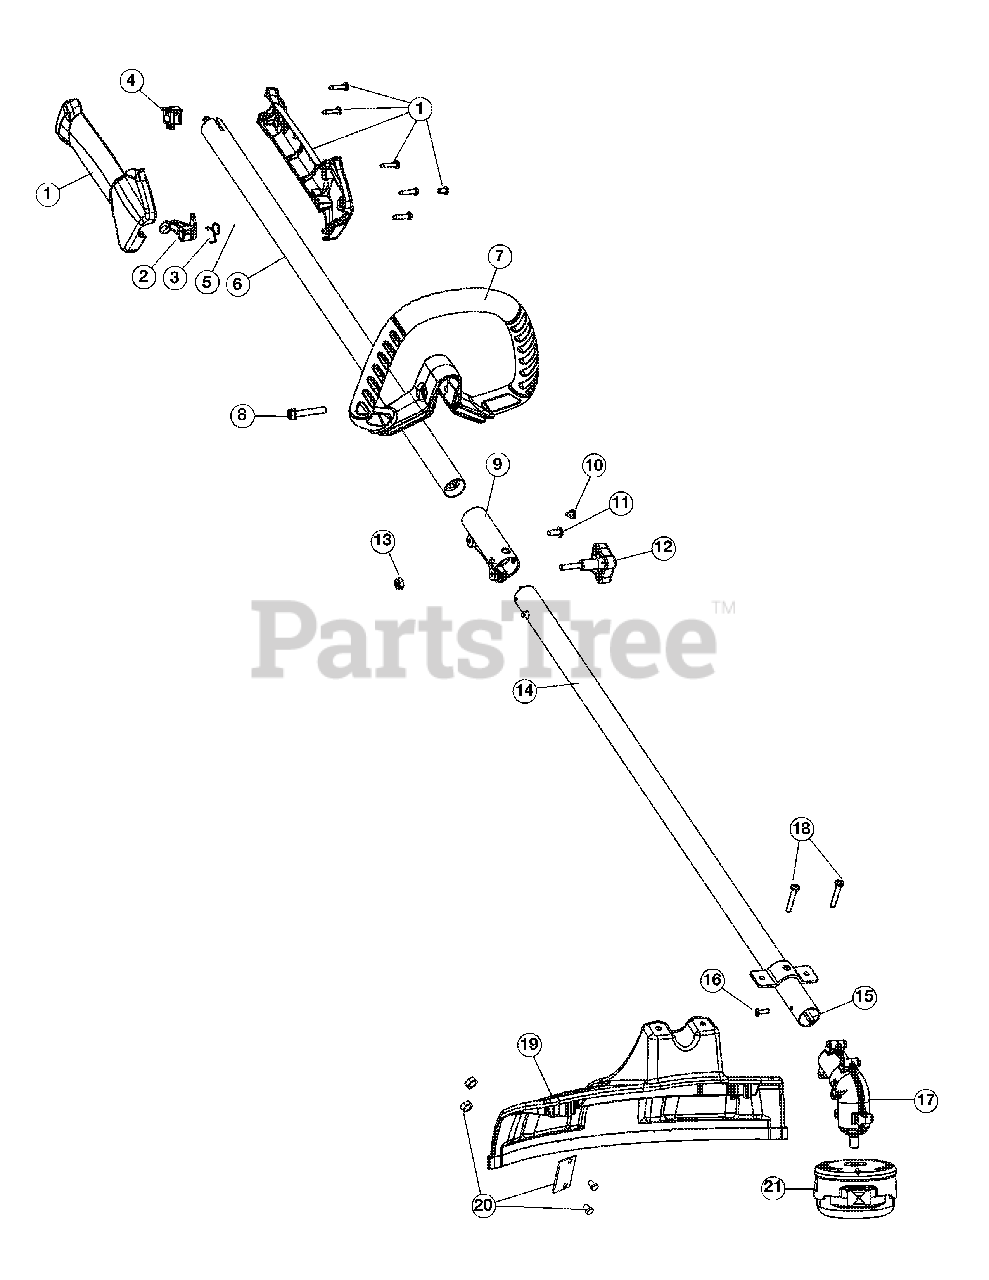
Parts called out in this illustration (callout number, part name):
1	Throttle Housing Assembly
2	Throttle Trigger
3	Throttle Trigger Spring
5	Throttle Cable Assembly
6	Upper Drive Shaft Housing Assembly
7	Deluxe D-Handle Assembly
9	Split Boom Coupler
12	Adjustment Knob
13	Knob Retaining Nut
14	Lower Drive Shaft Housing Assembly
15	Lower Flexible Drive Shaft
16	Anti-Rotation Screw
17	Gear Box Assembly
18	Shield Mounting Screws
19	Shield Assembly
20	Blade Assembly
21	Cutting Head Assembly
